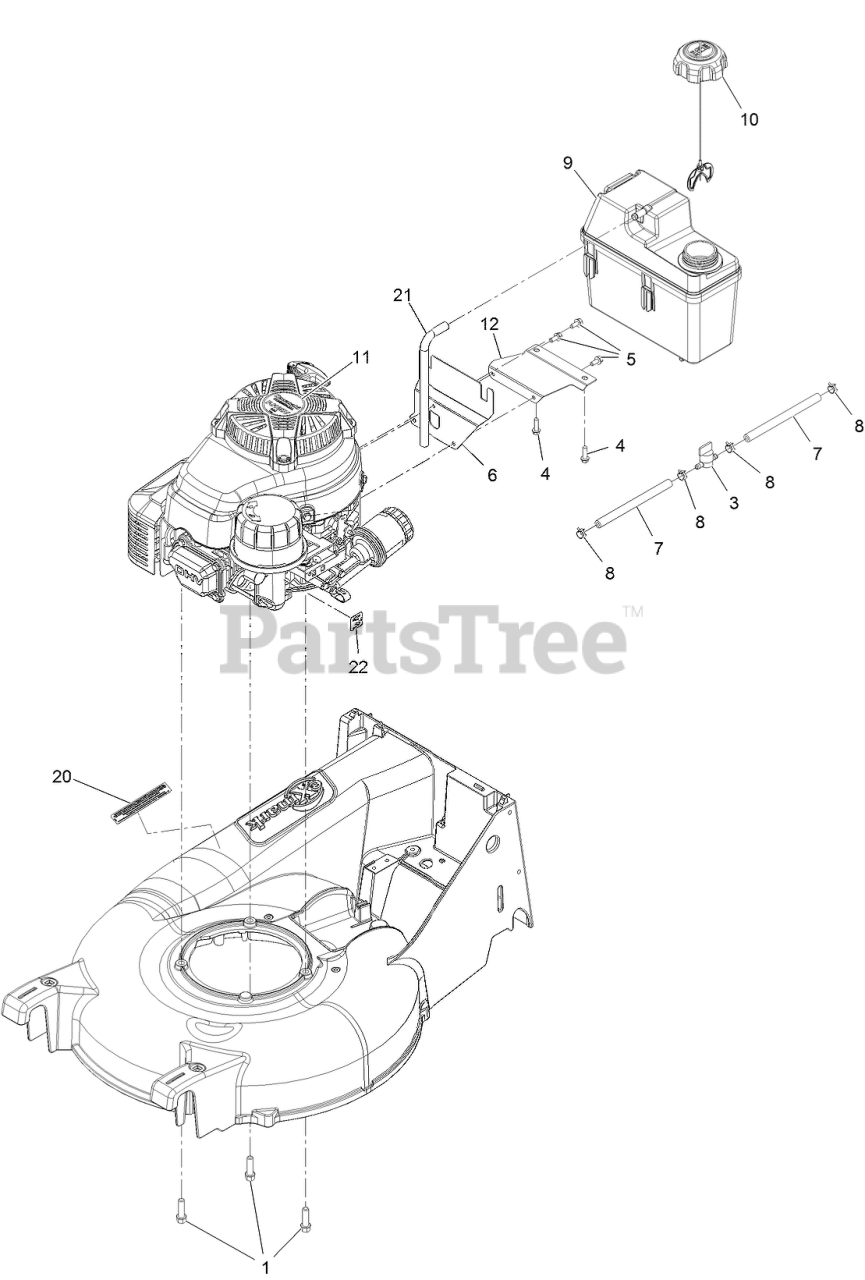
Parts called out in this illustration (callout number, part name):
1	SCREW-TAPTITE
3	VALVE-FUEL
4	SCREW-HWH
5	SCREW-HWH
6	BRACKET-TANK, MOUNTING
7	HOSE-FUEL
8	CLAMP-HOSE
9	TANK-FUEL
10	CAP-FUEL
12	BRACKET-TANK, SUPPORT
20	DECAL-ARRESTOR, SPARK
21	HOSE-VENT, CANISTER
22	DECAL-PRIMER
